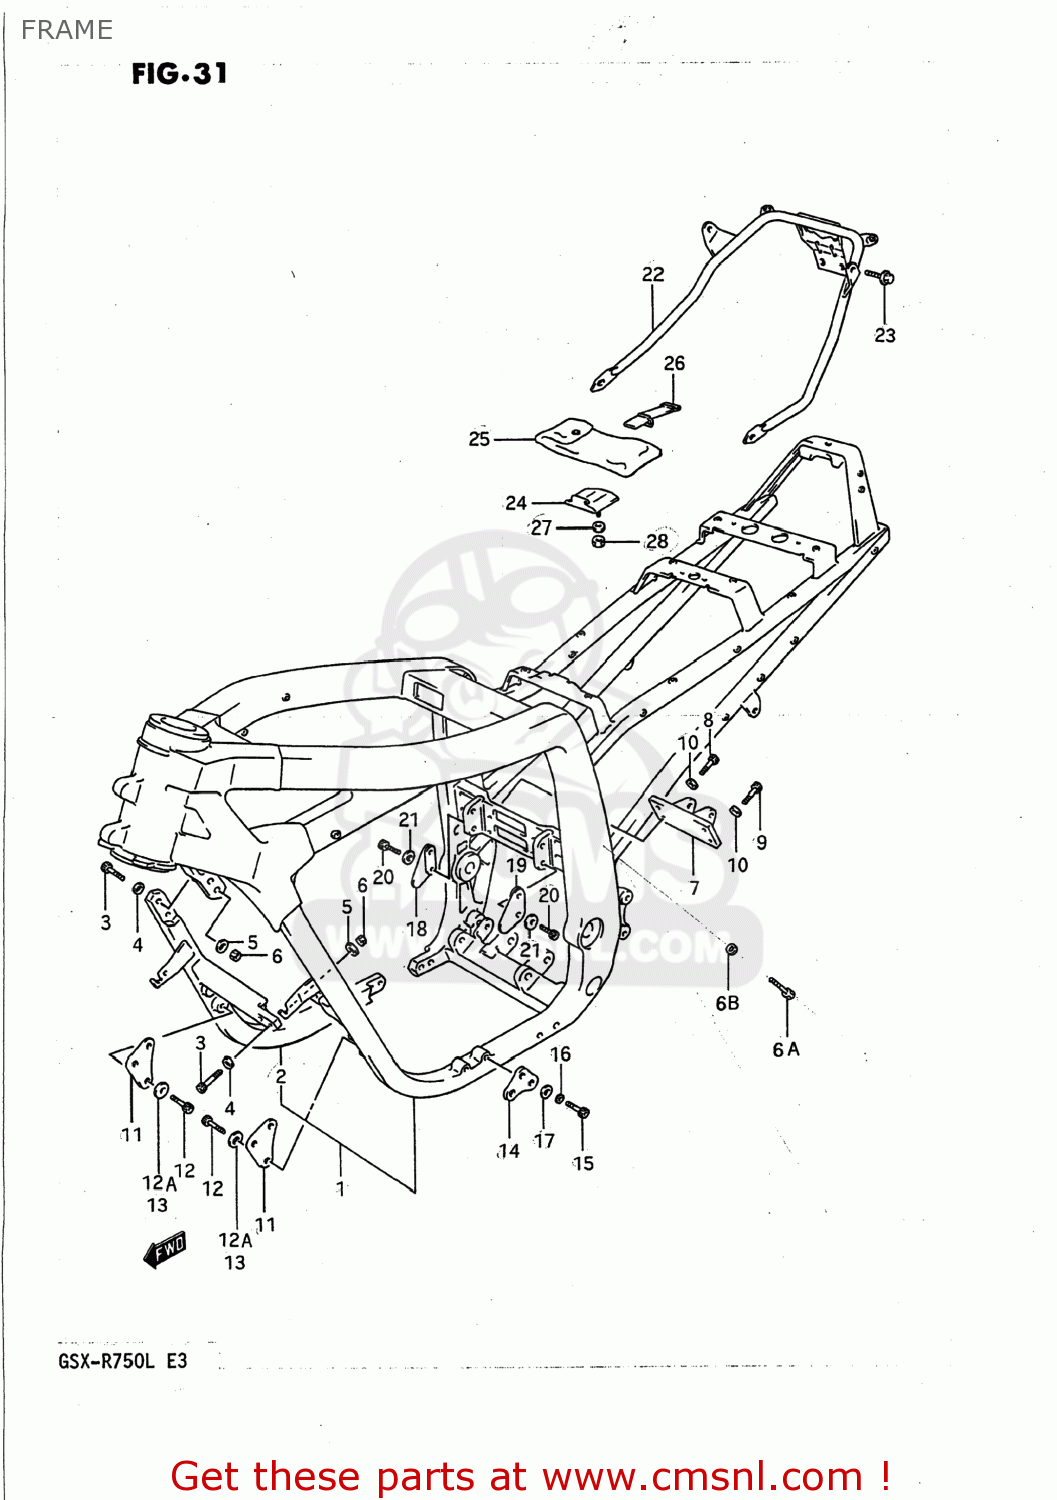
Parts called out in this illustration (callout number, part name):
1	FRAME
2	TUBE,FRAME
3	BOLT, LH
4	WASHER (10.1X21X2.3)
5	WASHER
6	NUT
6A	BOLT
6B	GASKET(6.2X11X1) (NAS)
7	BRACKET,RCU
8	BOLT 10X27
9	BOLT, LH
10	WASHER
11	PLATE,ENGINE MOUNTING
12	BOLT, FRONT LH
12A	WASHER,LOCK
13	WASHER (8.2X20X1.6)
14	PLATE,ENGINE MOUNT NO.2
15	BOLT, FRONT LH
16	WASHER,LOCK
17	WASHER (8.2X20X1.6)
18	PLATE,ENGINE MOUNTING NO
19	PLATE,ENGINE MOUNTING NO
20	BOLT(8X22)
21	WASHER (8.2X20X1.6)
22	GRIP
23	BOLT
24	HOLDER,TOOL
25	TOOL ASSY
26	BAND
27	WASHER
28	NUT 6MM
